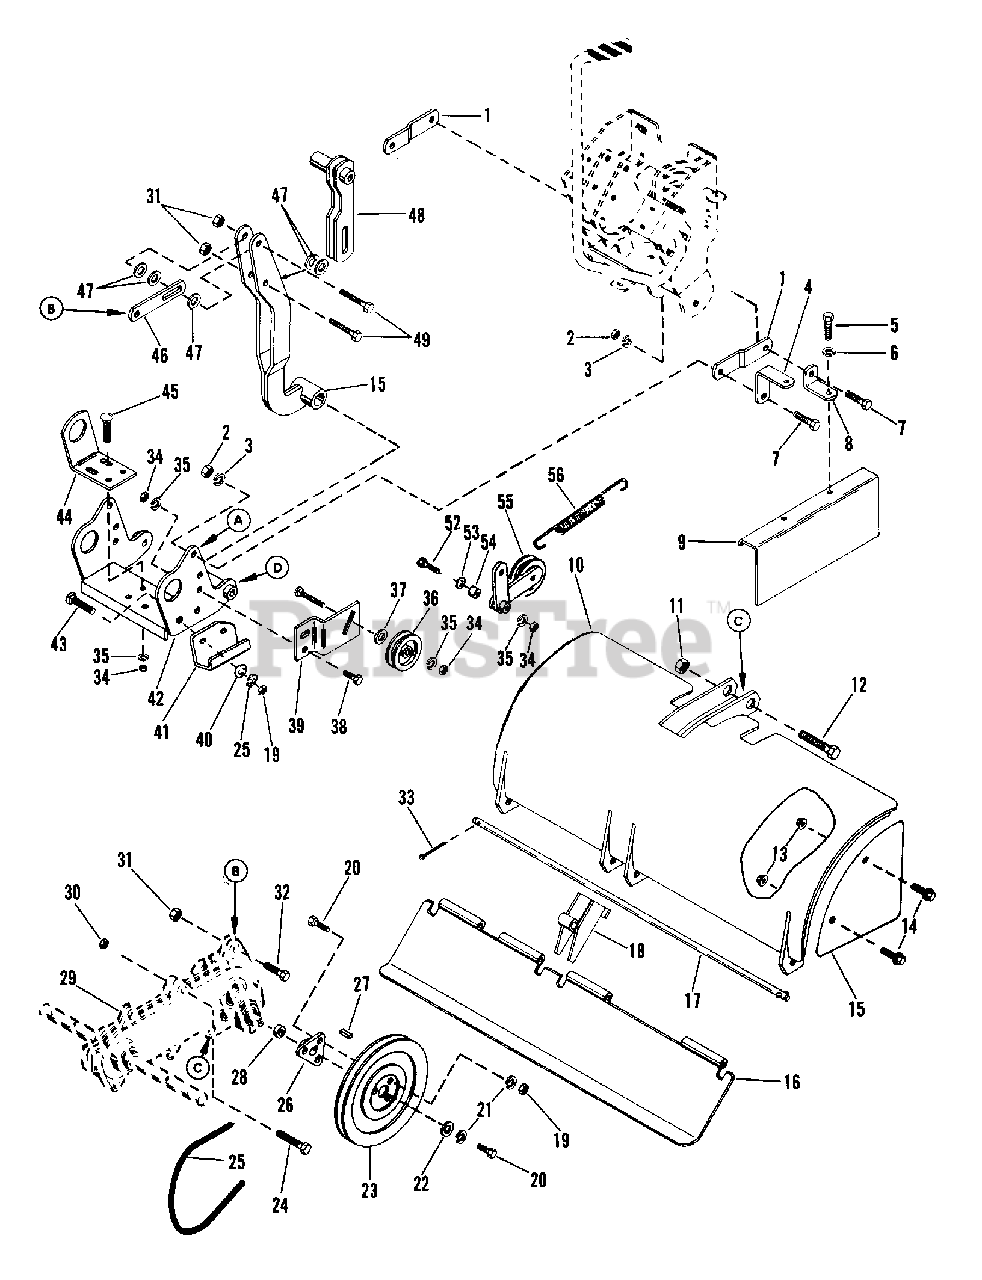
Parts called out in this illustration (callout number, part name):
1	SUPPORT ARM
2	NUT .50-13 PL
3	WSHR-LK .500X.151 HVY PL
4	GUARD BRACKET-REAR
5	BLT-HEX .25-20X.50 PL GR2
6	WSHR-LK .250X.077 HVY PL
7	BLT-HEX .50-13X1.25 PL GR2
8	GUARD BRACKET-FRONT
9	BELT GUARD
10	TINE HOOD W/DECALS
11	NUT-LK-CTR .75-10 PL
12	BLT-HEX .75-10X3.20 PL GR2
13	NUT-FLG. .312-18 PL
14	BLT-SERHFWH .31-18X.75 PL
15	SIDE PLATE
16	TAILBOARD
17	ROD-TAILBOARD HINGE
18	TAILBOARD STOP
19	NUT-HEX .312-18
20	BLT-HEX .31-18X.75 PL GR5
21	WSHR-LK .312X.097 PL HVY
22	WSHR-FL-STL .328X1.0X.094
23	PLY-? 9.0X1.25
24	BLT-HEX .31-18X3.00 PL GR5
25	BELT,4L RAW LAMINATED
26	HUB
27	KEY-SQ .188X.625X.188 SAE 61
29	CHAIN CASE ASSEMBLY
30	NUT-LK .312-18 GR A PL
31	NUT-LK-NYL .50-13 GR 5 PL
32	BLT-HEX .50-13X2.25 PL GR5
33	PIN-COTR .09X.75 PL
34	NUT-HEX .375-16
35	WSHR-LK .375X.115 HVY PL
36	IDLER-FLAT 2.75 X .38 DAYCO
37	WSHR-FL-STL .382X.812X.062
38	BLT-HEX .38-16X1.00 PL GR5
39	IDLER BRACKET
40	WSHR-FL-STL .323X.625X.062 PL
41	BELT GUARD
42	TILLER FRAME
43	BLT-RDHDSQNK .31-18X1.00 PL
44	MOUNTING BRACKET
45	BLT-RDHDSQNK .38-16X1.0 GR5PL
46	LIFT LINK
47	WSHR-FL-STL .511X1.441X.125 PL
48	CONTROL LINK
49	BLT-HEX .50-13X1.50 PL GR5
50	PIVOT ARM
51	BLT-RDHDSQNK .38-16X1.75 PL
52	BRG-BALL .250X.688X.312
53	WSHR-FL-STL .438X1.0X.083 PL
54	BUSHING, IDLER .380X.625X1.49
55	IDLER ARM
56	SG-TENS .120X1.0X4.46 WLD 47
